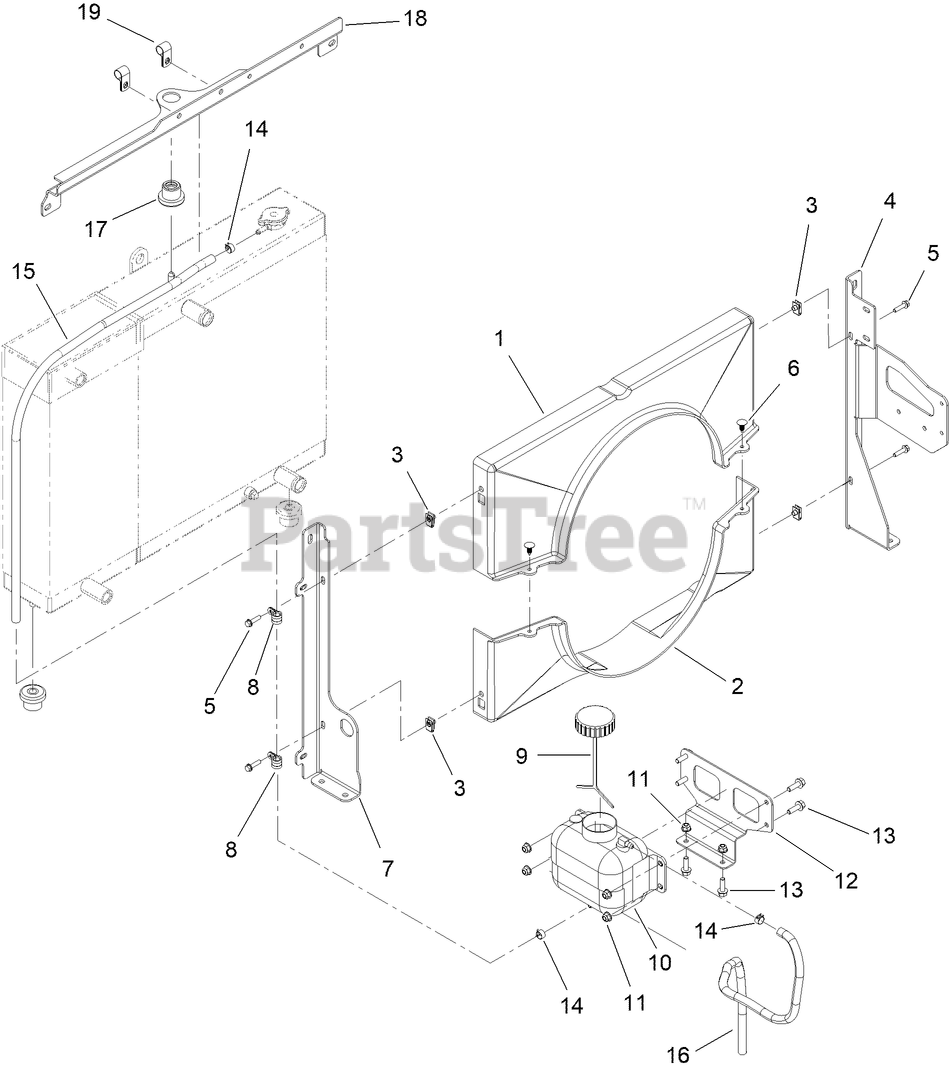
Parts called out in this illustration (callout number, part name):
1	SHROUD-TOP
2	SHROUD-BOTTOM
4	BRACKET-COOLING, RH
5	SCREW-HHF
6	PLUG-PLASTIC
7	BRACKET-COOLING, LH
8	CLAMP-R
9	CAP-RESERVOIR
10	TANK-RECOVERY, COOLANT
11	NUT-HF, NI
12	RES. BRACKET
13	SCREW-HHF
14	CLAMP-HOSE
15	HOSE-FUEL
16	HOSE-FUEL
17	MOUNT-ISOLATOR
18	BRACKET-COOLING, TOP
19	CLAMP-R
